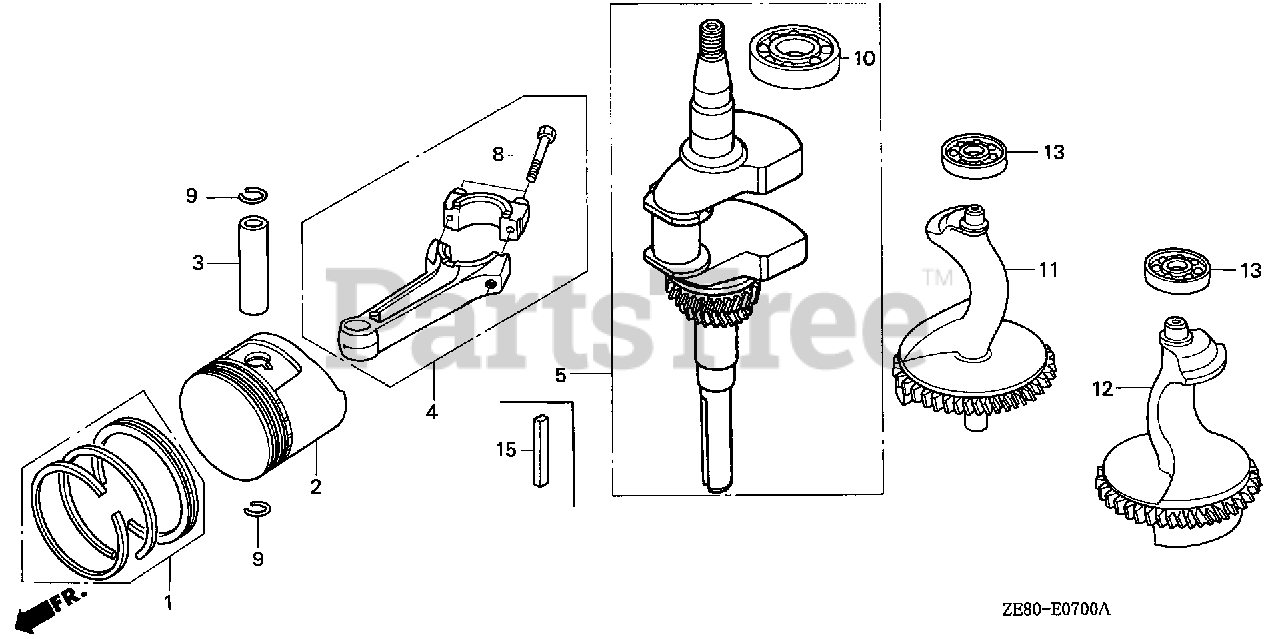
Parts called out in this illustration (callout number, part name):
1	RING SET, PISTON (STD) (NIPPON)
1	RING SET, PISTON (STD)
1	RING SET, PISTON (STD) (NIPPON) (NOT AVAILABLE)
1	RING SET, PISTON (0.25) (NIPPON)
1	RING SET, PISTON (0.25)
1	RING SET, PISTON (0.25) (NIPPON) (NOT AVAILABLE)
1	RING SET, PISTON (0.50) (NIPPON)
1	RING SET, PISTON (0.50)
1	RING SET, PISTON (0.50) (NIPPON) (NOT AVAILABLE)
1	RING SET, PISTON (0.75) (NIPPON)
1	RING SET, PISTON (0.75)
2	PISTON (STD)
2	PISTON (0.25)
2	PISTON (0.50)
2	PISTON (0.75)
3	PIN, PISTON
4	ROD ASSY., CONNECTING
4	ROD ASSY., CONNECTING (0.25 LOWER SIZE)
5	CRANKSHAFT (NOT AVAILABLE)
8	BOLT, CONNECTING ROD
9	CLIP, PISTON PIN (18MM)
10	BEARING, RADIAL BALL (6206)
11	WEIGHT A, BALANCER
12	WEIGHT B, BALANCER
13	BEARING, RADIAL BALL (6202)
